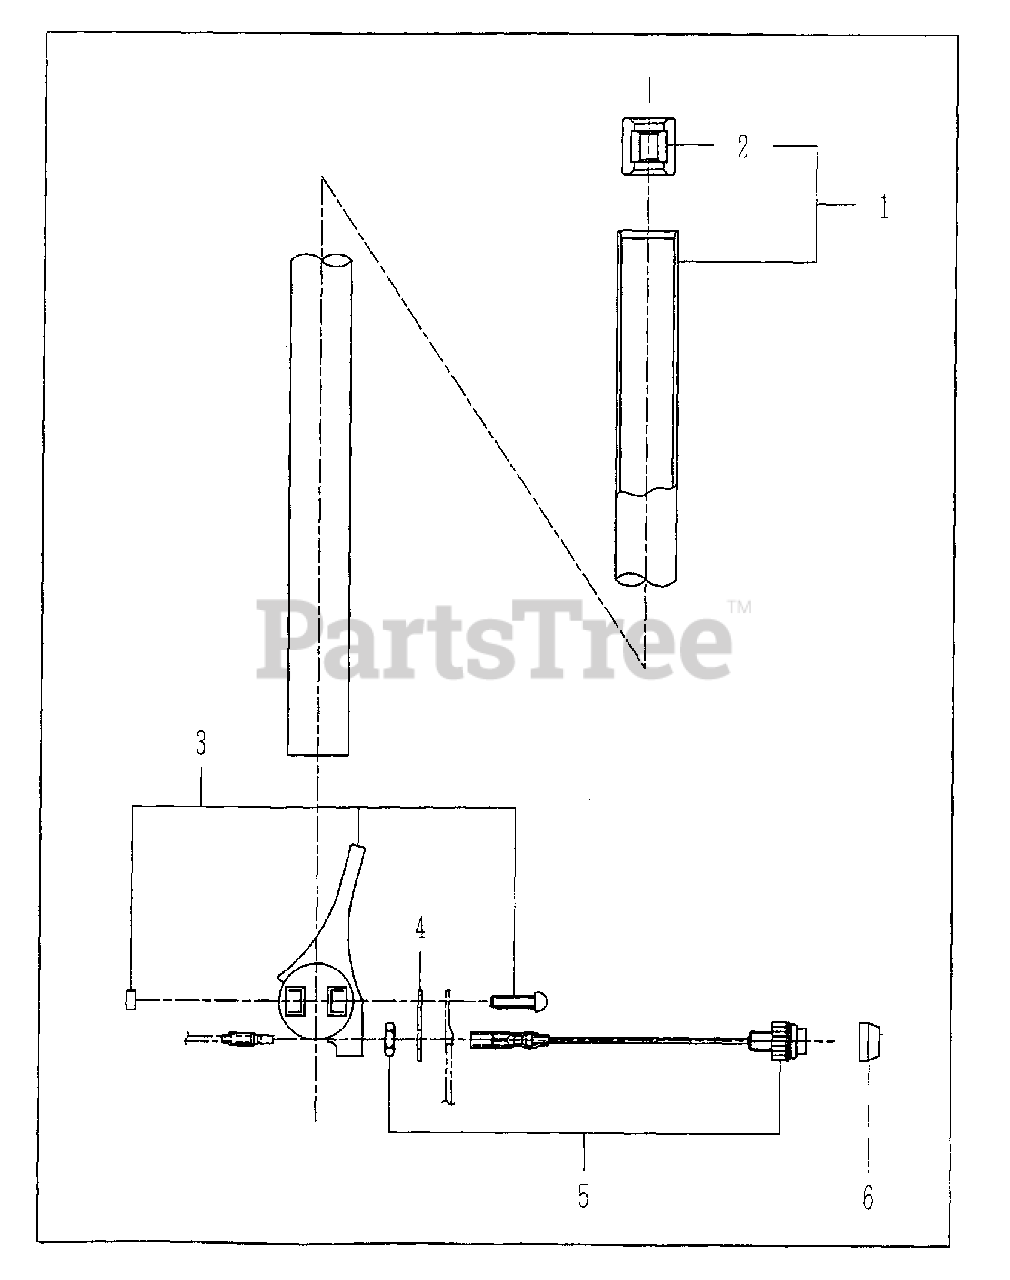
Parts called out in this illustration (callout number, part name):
1	PIPE, MAIN
3	LEVER, THROTTLE
5	SWITCH
6	CAP
